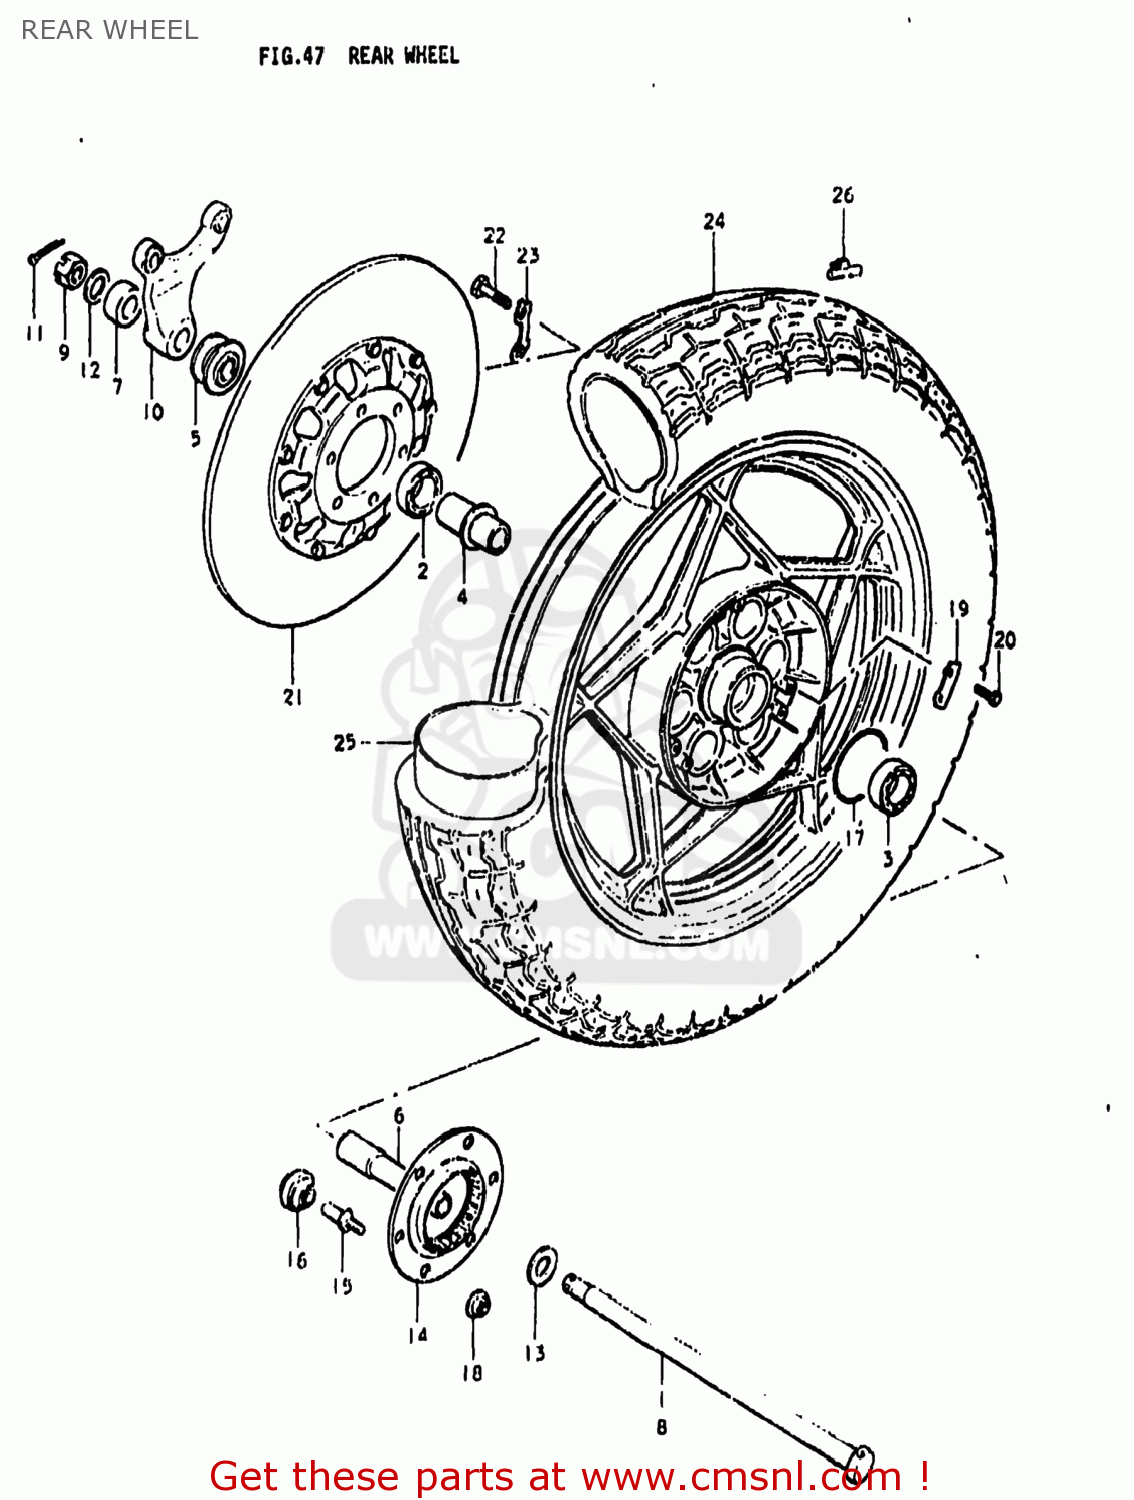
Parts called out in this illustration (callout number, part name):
1	WHEEL,REAR
2	BEARING
3	BEARING
4	SPACER,REAR HUB BEARING
5	SPACER,REAR AXLE
6	SPACER,REAR AXLE,LEFT
7	SPACER (17X33X15.2)
8	AXLE,REAR
9	NUT
10	BRACKET,RR,CALIPER
11	PIN,COTTER
12	WASHER
13	WASHER (17.5X36X3.2)
14	JOINT, DRIVEN
15	BOLT
16	BUSH
17	O RING(D:2.1,ID:65)
18	NUT
19	WASHER
20	BOLT, UPPER
21	DISC,BRAKE
22	BOLT(8X30)
23	WASHER
24	TIRE
25	TUBE ASSEMBLY,WHEEL,INNER
26	BALANCER,WHEEL
